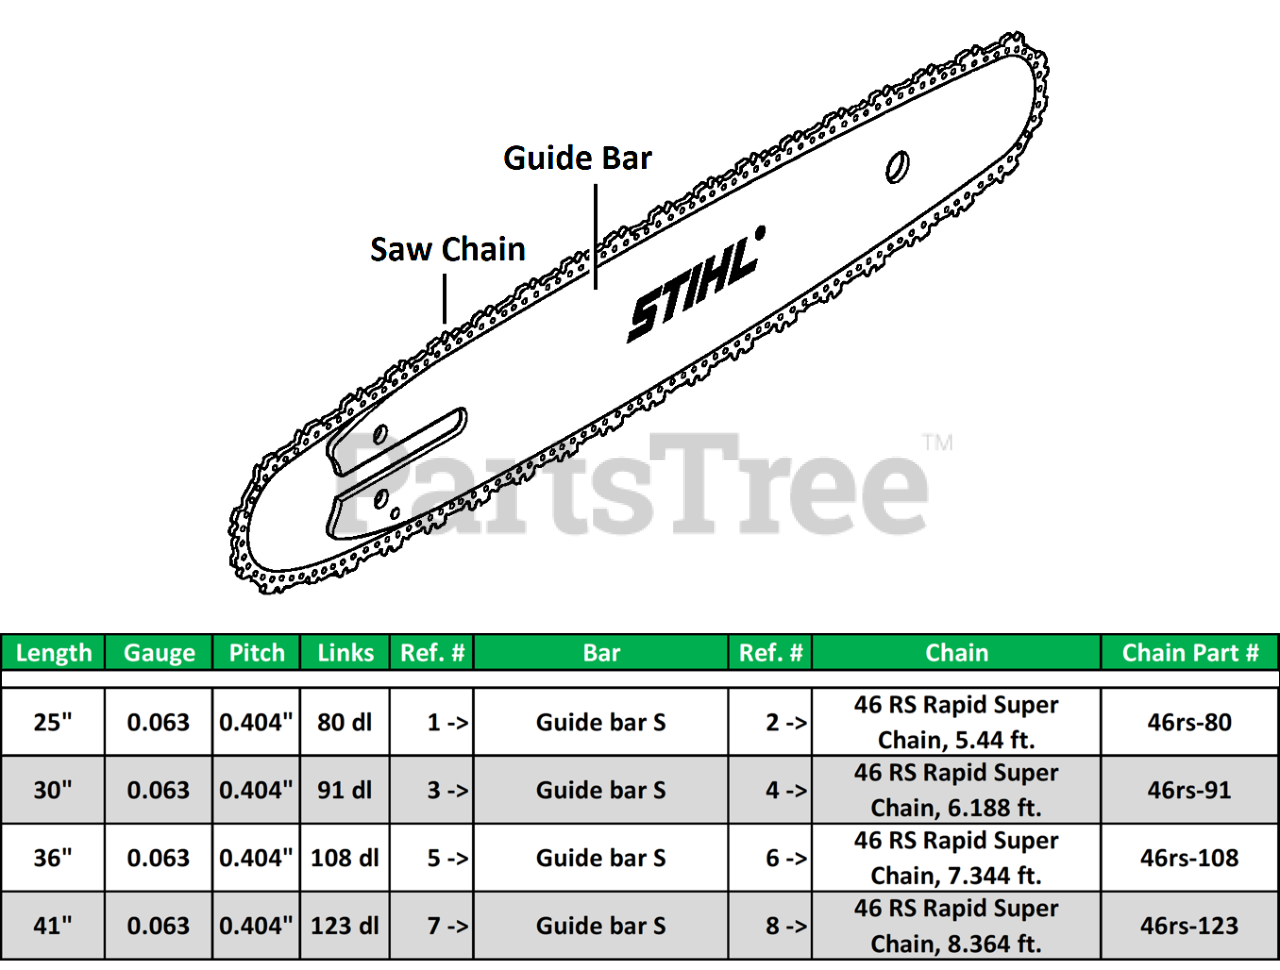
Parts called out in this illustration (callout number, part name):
1	Guide bar S 63cm/25" 1,6mm/0.063" .404"
2	46 RS Rapid Super Chain, 5.44 ft.
3	Guide bar S 75cm/30" 1,6mm/0.063" .404"
4	46 RS Rapid Super Chain, 6.188 ft.
5	Guide bar S 90cm/36" 1,6mm/0.063" .404"
6	46 RS Rapid Super Chain, 7.344 ft.
7	Guide bar S 105cm/41" 1,6mm/0.063" .404"
8	46 RS Rapid Super Chain, 8.364 ft.
